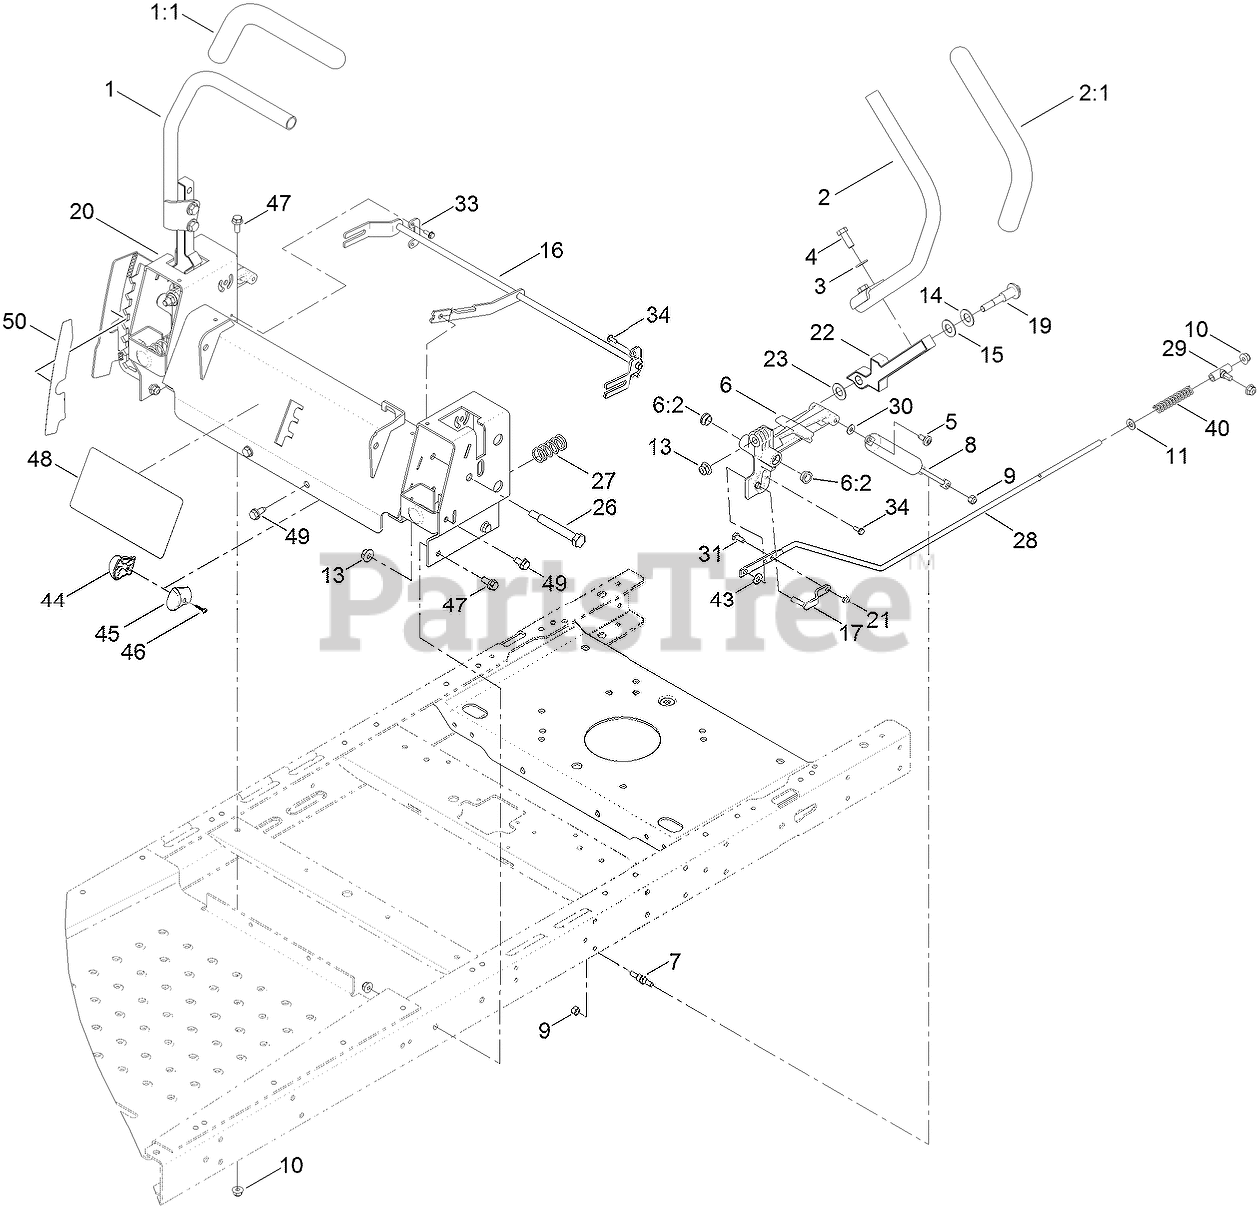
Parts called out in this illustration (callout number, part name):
1	HANDLE-CONTROL, RH
2	HANDLE-CONTROL, LH
3	WASHER-FLAT
4	SCREW-HH
5	SCREW-SHOULDER
6	ACTUATOR ARM ASM
6:2	BUSHING-FLANGE
7	STUD-DAMPER
8	DAMPER
9	NUT-LOCK, NI
10	NUT-HF, NI
11	WASHER-PLAIN
13	NUT-HF, NI
14	WASHER-BELLEVILLE
15	WASHER
16	SPEED CONTROL ASM
17	PIN-ROD, HYDRO
19	BOLT-PIVOT
20	CONTROL BOX ASM
21	NUT-LOCK, NI
22	LEVER-CONTROL
23	WASHER-NYLON
26	BOLT-PIVOT
27	SPRING-RETURN
28	ROD-HYDRO
29	MOUNT-ROD, HYDRO
30	WASHER
31	SCREW-HH
33	RETAINER
34	SCREW-TAPTITE
40	SPRING-RETURN, NEUTRAL
43	SPACER-NYLON
44	KNOB-RH
45	KNOB-LH
46	SCREW-PPH
47	SCREW-HHF
48	DECAL-CONTROL, SPEED
49	SCREW-HWHTF
50	DECAL-HOC, CE
